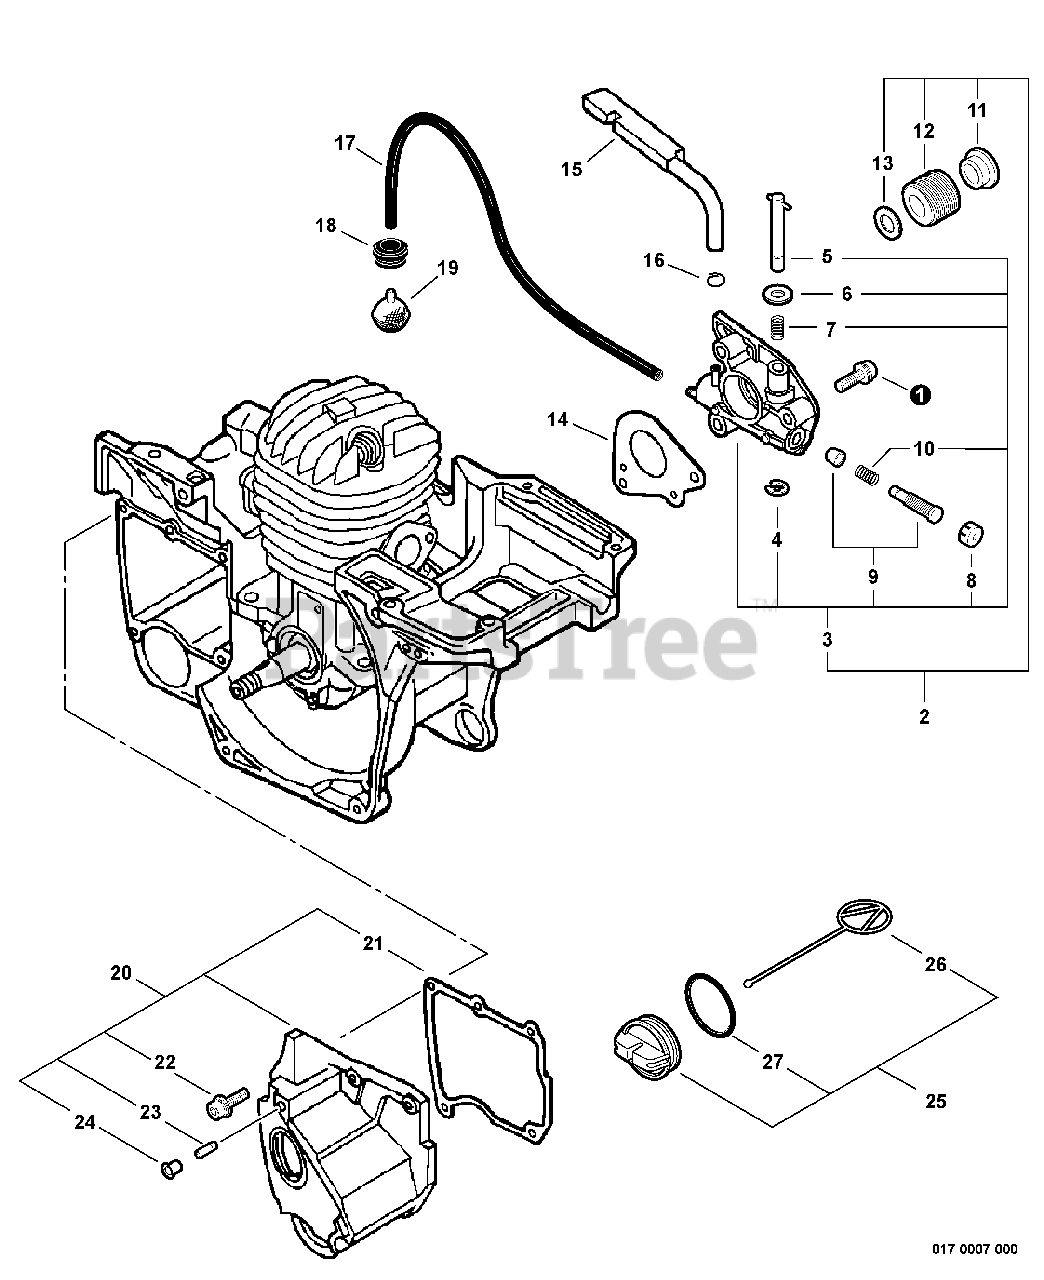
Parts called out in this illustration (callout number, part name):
1	SCREW - 4X16
2	AUTO-OILER ASSY
3	AUTO-OILER ASSY
4	RING, RETAINING
5	NEEDLE, ADJUST
8	CAP, OIL PUMP
9	PLUNGER ASSY
10	SPRING, PLUNGER
11	COLLAR - 10
12	GEAR - WORM
13	WASHER - 11
14	SEAL, DUST
15	PIPE - OIL
16	CLIP - 6.5
17	PIPE - OIL
19	FILTER, OIL
20	OIL TANK ASSY
21	GASKET, OIL TANK
22	SCREW - 4X16
23	VENT, TANK
25	CAP ASSY - BLACK
26	CONNECTOR, CAP
27	O-RING - 25
